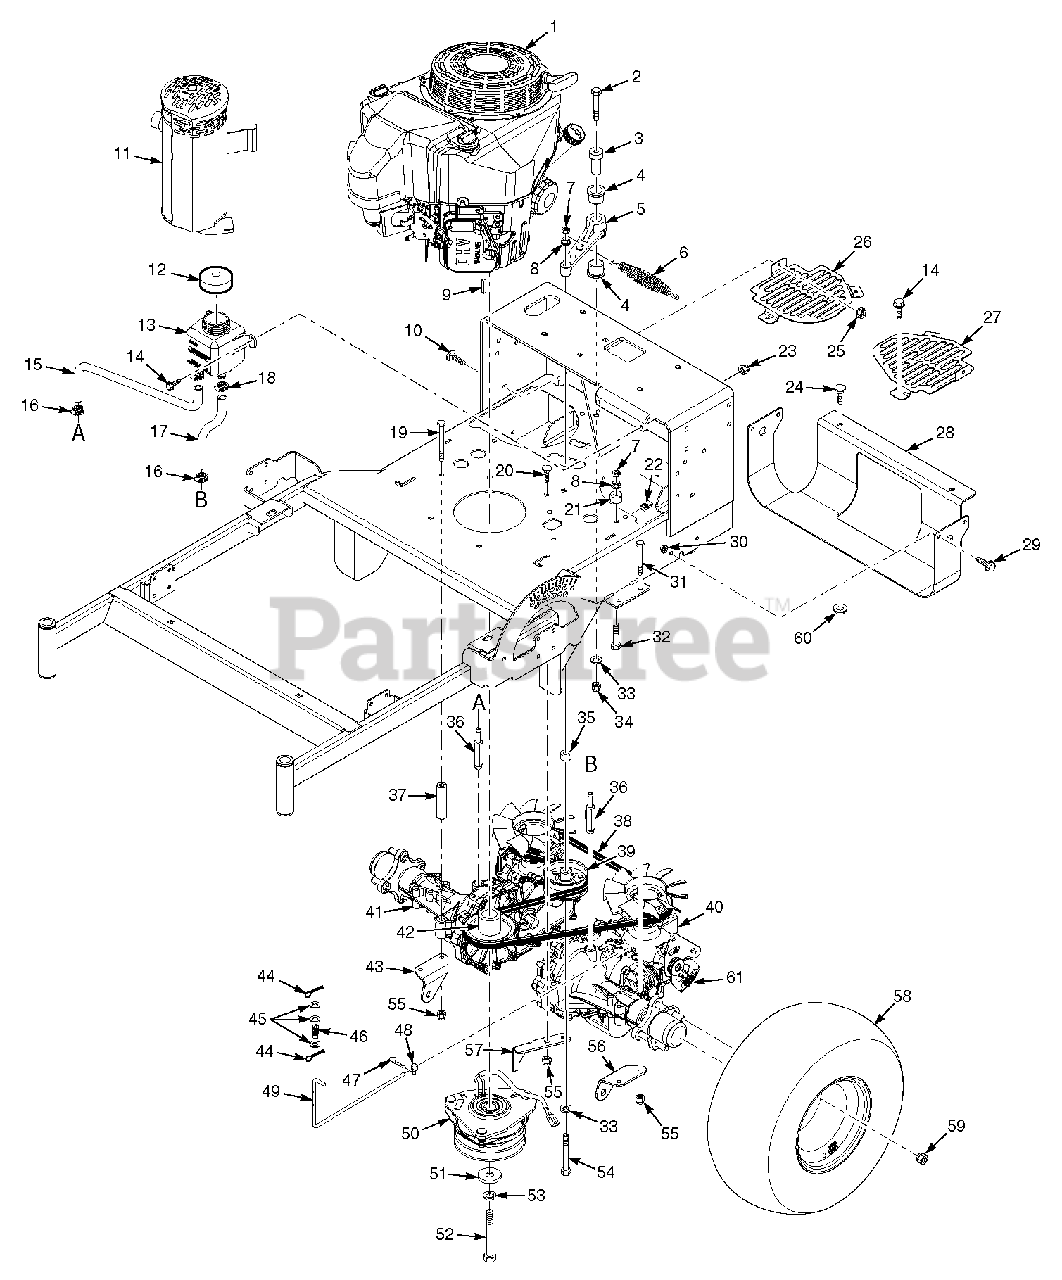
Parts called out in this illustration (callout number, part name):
1	Engine, Kawasaki FS481V
1	Engine, Kawasaki FS541V
1	Engine, Kawasaki FS600V (Recoil Start)
1	Engine, Kawasaki FS600V (Electric Start)
1	Engine, Kawasaki FS651V (Electric Start)
2	Bolt, Hex Head 3/8-16 x 3"
3	Pivot, Idler
4	Bearing
5	Idler Arm
6	Spring, Transmission Idler
7	Nut, Center Lock 3/8-16
8	Nut, Serrated Flange 3/8-16
9	Key, 1/4 x 1/4 x 2-1/2"
10	Bolt, Carriage 1/4-20 x 3/4"
11	Muffler, Kawasaki (FS481, FS541, FS600)
11	Muffler, Kawasaki (FS651) - SWZT61
11	Manifold, Kawasaki (FS651) - SWZT61
13	Reservoir Assembly
14	Bolt, Hex Head, Serrated Flng 1/4-20 x 3/4"
15	Hose, RH Transmission
16	Clamp, 0.69" Max Dia.
17	Hose, LH Transmission
18	Clamp, 0.87" Max Dia.
19	Bolt, Hex Head 5/16-18 x 6-1/2"
20	Bolt, Carriage 5/16-18 x 1"
21	Spacer
22	U-Nut, 1/4-20
23	Nut, Elastic Stop 1/4-20
24	Bolt, Carriage 5/16-18 x 3/4
25	Nut, Serrated Flange 1/4-20
26	Fan Cover, RH
27	Fan Cover, LH
28	Skid Plate
29	Cpscrw, 5/16-18 x 3/4"Serrated Flange HH
30	Nut, Serrated Flange 5/16-18
31	Bolt, Hex Head 5/16-18 x 3"
32	Bolt, Hex Head 3/8-16 x 1-3/4"
33	Flatwasher, 3/8-.391 x .938 x .105 Hardened
34	Nut, Elastic Stop 3/8-16
35	Spacer
36	Fitting, Transmission
37	Spacer, Axle
38	Belt, Transmission Drive
39	Pulley, 3-1/2" Dia.
40	Transaxle Assy., (ZH-GMCC-3LUB-1MXX)
41	Transaxle Assy., (ZH-KMCC-3LUC-1MXX)
42	Pulley, 4-1/2" Dia. 1" Bore
43	Pusharm Mount Bracket, RH
44	Cotter Pin, 3/32 x 1"
45	Flatwasher, 1/4-.312 x .750 x .065
46	Spring, Dump Valve Link
47	Pin, Rue Cotter 3/8" Dia.
48	Joint, Swivel
49	Link, Dump Valve
50	Electric Clutch Assembly
51	Flatwasher, 7/16-.469 x 1.75 x .25
52	Bolt, Hex Head 7/16-20 x 3" w/t Patch
53	Lockwasher, 7/16" spring
54	Bolt, Hex Head 3/8-16 x 3-3/4"
55	Nut, Elastic Stop 5/16-18
56	Pusharm Mount Bracket, LH
57	Bracket, Anti-Rotation
58	Wheel Assembly 18 x 6.5-8 (36" Only)
58	Tire 18 x 6.5-8 (36" Only)
58	Wheel Assembly 18 x 8.5-8
58	Tire 18 x 8.5-8
59	Wheel Nut, 1/2-20
60	Nut, Push-On 5/16-18
61	Spring, RTN
